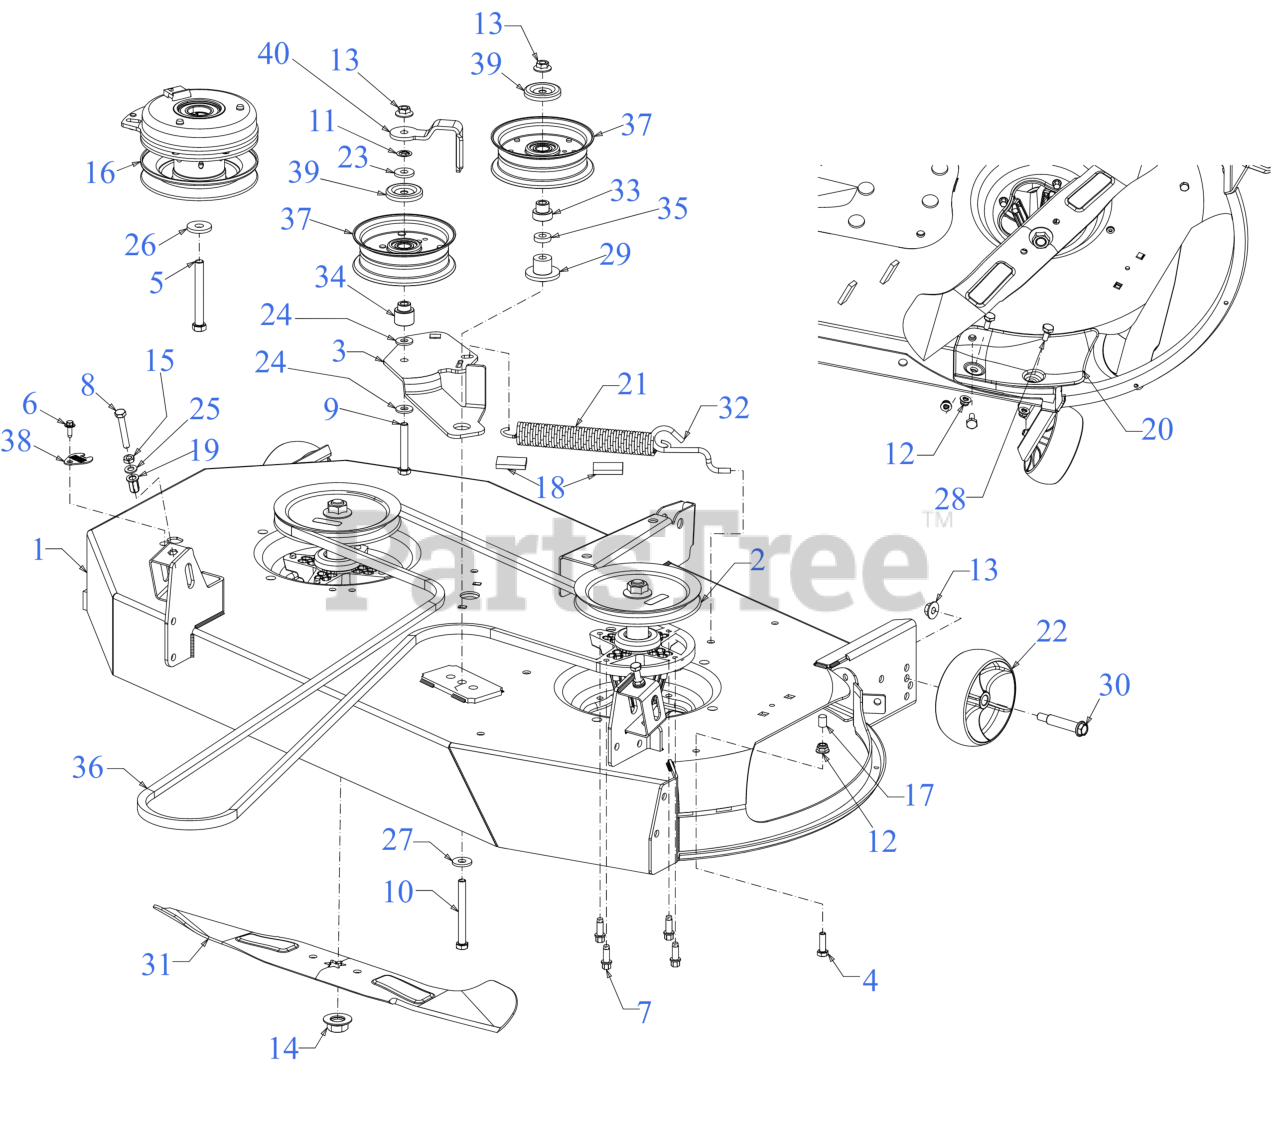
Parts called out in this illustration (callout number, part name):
1	46" FAB DECK SHELL
2	SPINDLE ASSEMBLY
2	Cub Cadet 46" SPINDLE ASSEMBLY (05078A)
3	46" DECK IDLER BRACKET
4	SCREW 5/16-18 x 1.0 GR5
5	SCREW 7/16-20 x 3.5 GR5
6	SCREW M6-1 x .625
7	SCREW 5/16-18 x .875
8	SCREW-FULL THREAD 5/16-18 GR5
9	HEX SCREW-3/8-16X2.5 GR5
10	SCREW 3/8-16 x 3.50 GR5
12	FLANGE LOCK NUT 5/16-18
13	FLANGE LOCK NUT
14	FLANGE NUT 5/8-18
16	ELECTRIC PTO CLUTCH
18	FOAM TAPE .75" WIDE x .25" THICK
19	NUT RIVET 5/16-18
20	DISCHARGE BAFFLE
21	EXTENSION SPRING
22	DECK WHEEL (5.0 DIA x 1.875)
23	FLAT WASHER .385 x 1.00 x .135
24	FLAT WASHER .385X.870X.090
25	FLAT WASHER
26	FLAT WASHER .445 x 1.248 x .170
27	FLAT WASHER .406ID X1.0 OD
28	SHOULDER SCREW
29	SHOULDER SPACER
30	SHOULDER BOLT (.50 X 2.0 x 3/8 -16)
31	23.25" BLADE (HIGH LIFT)
31	Cub Cadet 46" BLADE SET
31	Genuine Factory Parts 46" HI LIFT BLADE SET
32	DECK SPRING HOOK
33	SHOULDER SPACER
34	SHOULDER SPACER
36	V-BELT A SEC x 120.8
36	Cub Cadet 46" RZT DECK BELT
36	Troy-Bilt 46" RZT DECK BELT
37	IDLER PULLEY 4.50" DIA
38	DECK WASH PLUG
39	IDLER PULLEY CAP
40	BELT KEEPER
